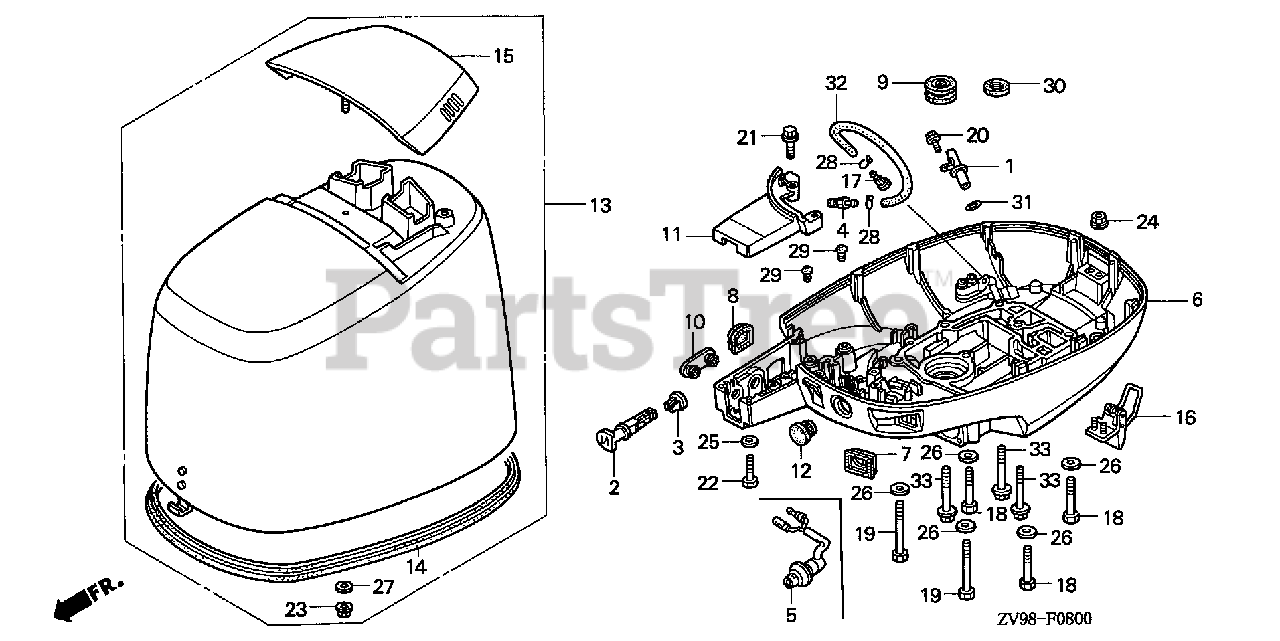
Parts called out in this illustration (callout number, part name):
1	PIPE, OIL LEVEL
2	KNOB, CHOKE
3	GUIDE, CHOKE KNOB
4	JOINT, WATER HOSE
6	CASE, ENGINE (LOWER) *NH282MU* (OYSTER SILVER METALLIC-U)
7	GROMMET, CASE (LOWER) (B)
8	GROMMET, CASE (LOWER) (C)
9	GROMMET, OIL CASE (E)
10	GROMMET, CASE (LOWER) (F)
11	CASE, SEPARATE *NH282MU* (OYSTER SILVER METALLIC-U)
12	CAP, HANDLE (LOWER)
13	COVER, ENGINE *NH282MU* (OYSTER SILVER METALLIC-U)
14	SEAL, ENGINE COVER
15	HANDLE, TILT *NH282MU* (OYSTER SILVER METALLIC-U)
16	LEVER, FASTENER
17	GROMMET, WATER CHECK
18	BOLT, HEX. (8X55)
19	BOLT, HEX. (8X80)
20	BOLT, FLANGE (6X20)
21	BOLT, FLANGE (6X28) (CT200)
22	BOLT, HEX. (6X45)
23	NUT, U (6MM)
24	NUT, SELF-LOCK (6MM)
25	WASHER, PLAIN (6MM)
26	WASHER, PLAIN (8MM)
27	WASHER (6MM)
28	CLIP, TUBE (B8)
29	PLUG, CHANGE REINFORCEMENT
30	SEAL, WATER (17X26X7)
31	O-RING (11.5X3.5)
32	BULK HOSE, VACUUM (4.5X1000) (4.5X330)
33	BOLT, FLANGE (8X70)
